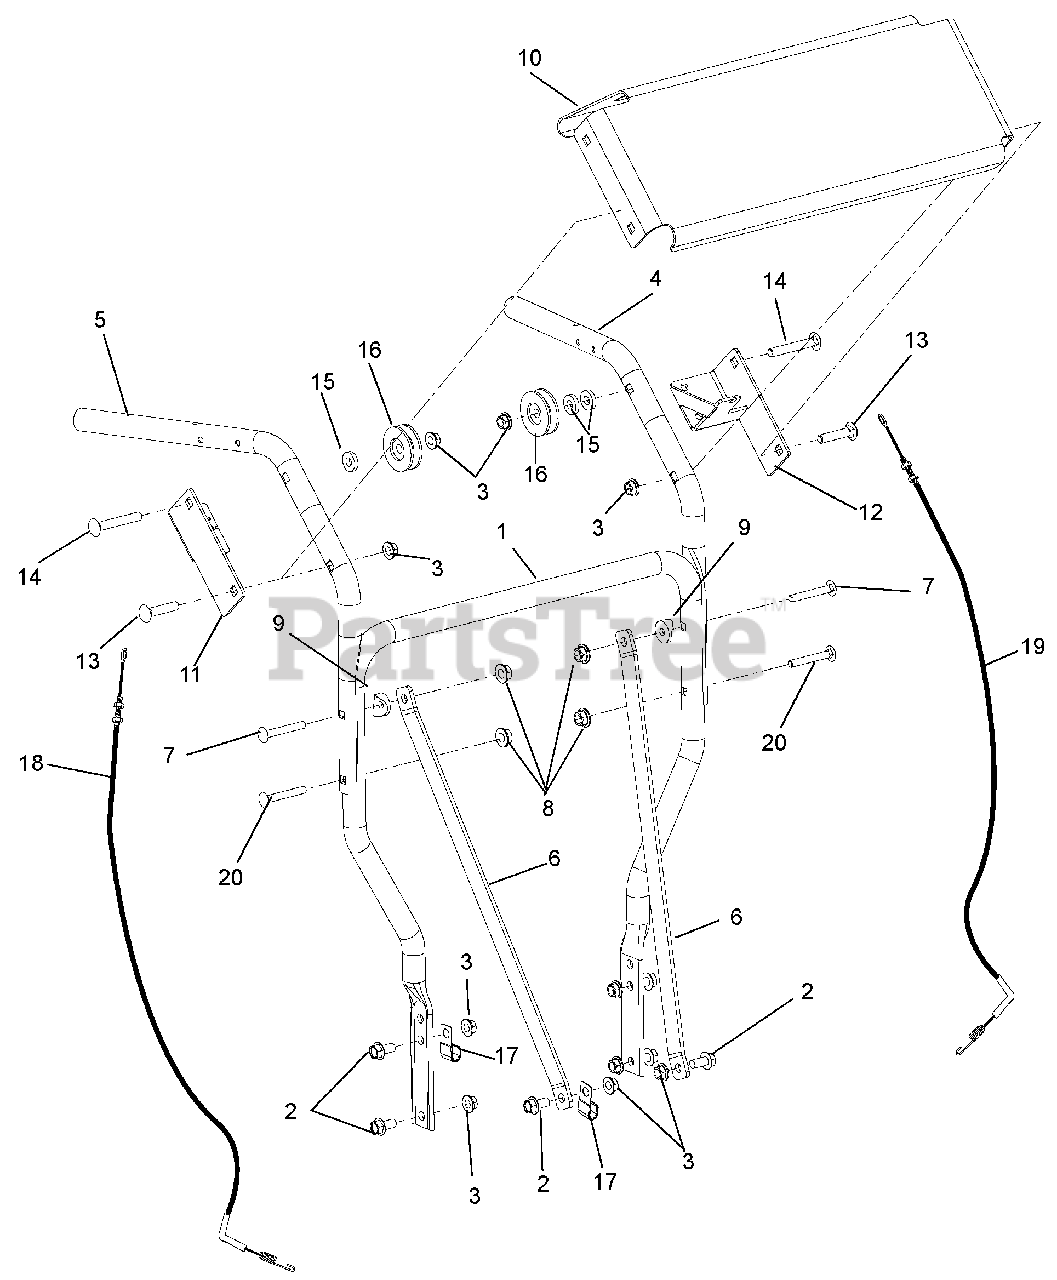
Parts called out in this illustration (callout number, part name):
1	HANDLEBAR, LOWER
2	BLT-SERHFWH .38-16X.75 YWZC
3	@NUT-LK-TOP-FLG .38-16 YWZC
4	WMT-HANDLEBAR, UPPER LH
5	HANDLEBAR, UPPER RH
6	BRKT-BRACE, HANDLEBARS
7	@BLT-RDHDSQNK .31-18X2.25 G5YZ
8	@NUT-LK-NYL-FLG .31-18 YWZC
9	SPACER, HANDLEBAR
10	CONSOLE, WAW
11	MOUNT, P-BRAKE CABLE (WLDMNT)
12	MOUNT, WAW PTO CABLE (WLDMNT)
13	@BLT-RDHDSQNK .38-16X1.75 G5YZ
14	@BLT-RDHDSQNK .38-16X2.50 G5YZ
15	WSHR-FL-STL .390X.88X.18 YWZC
16	IDLER, 3L FRONT SIDE .38X1.875
17	J-CLAMP
18	CABLE-BRAKE CONTROL
19	CABLE-PTO CONTROL
20	@BLT-RDHDSQNK .31-18X1.75 G5YZ
